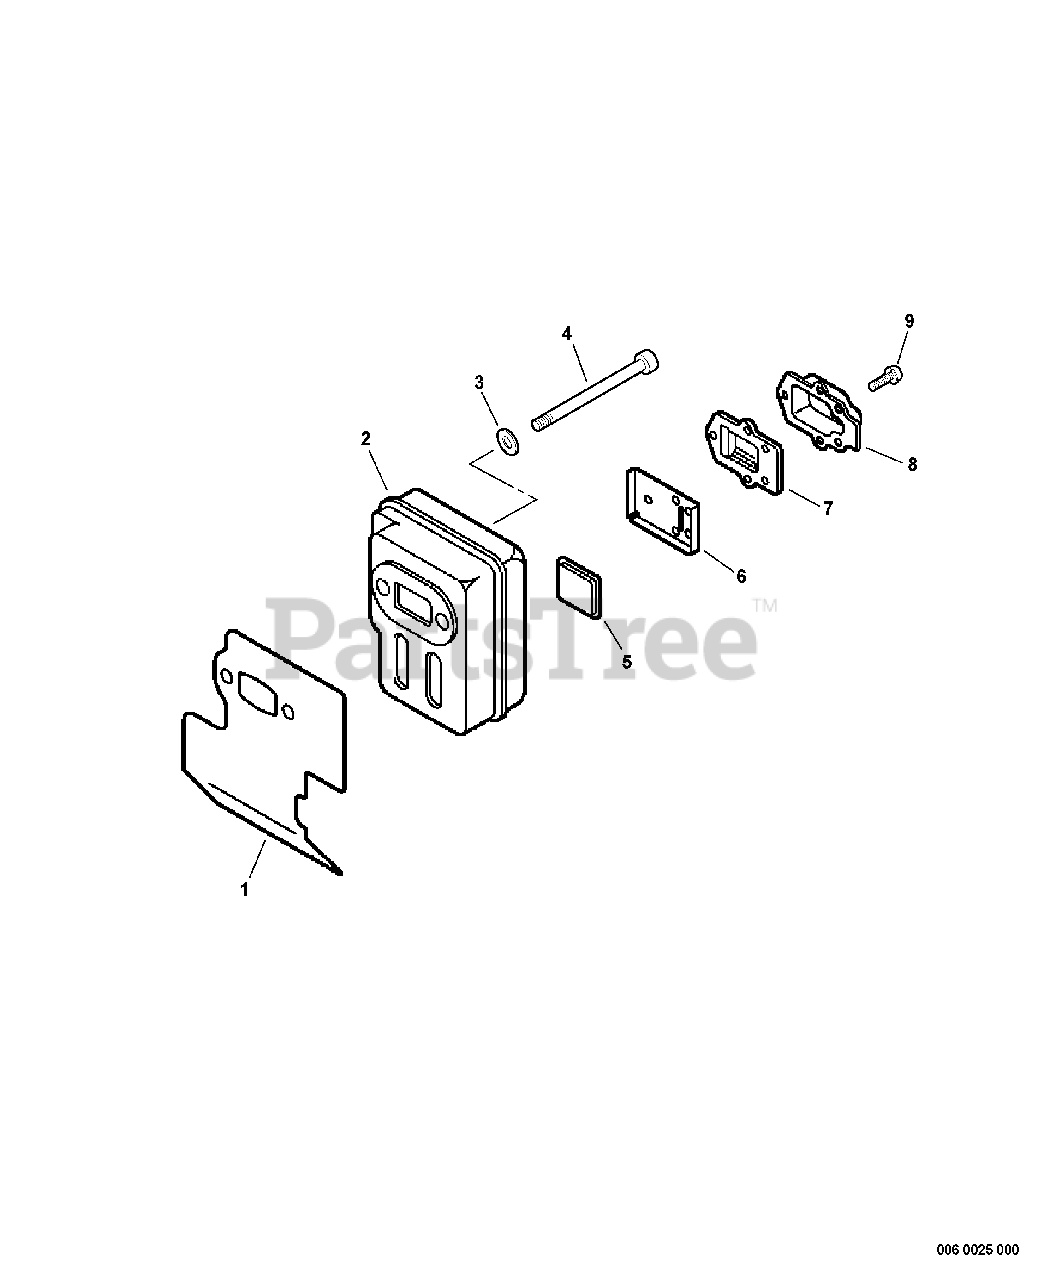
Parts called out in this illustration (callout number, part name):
1	GASKET, EXHAUST
2	MUFFLER
3	WASHER - 5
4	SCREW - 5X55
5	SCREEN, SPARK ARRESTOR
6	GASKET, EXHAUST
7	GUIDE, EXHAUST - INNER
8	GUIDE, EXHAUST - OUTER
9	SCREW - 4X12
